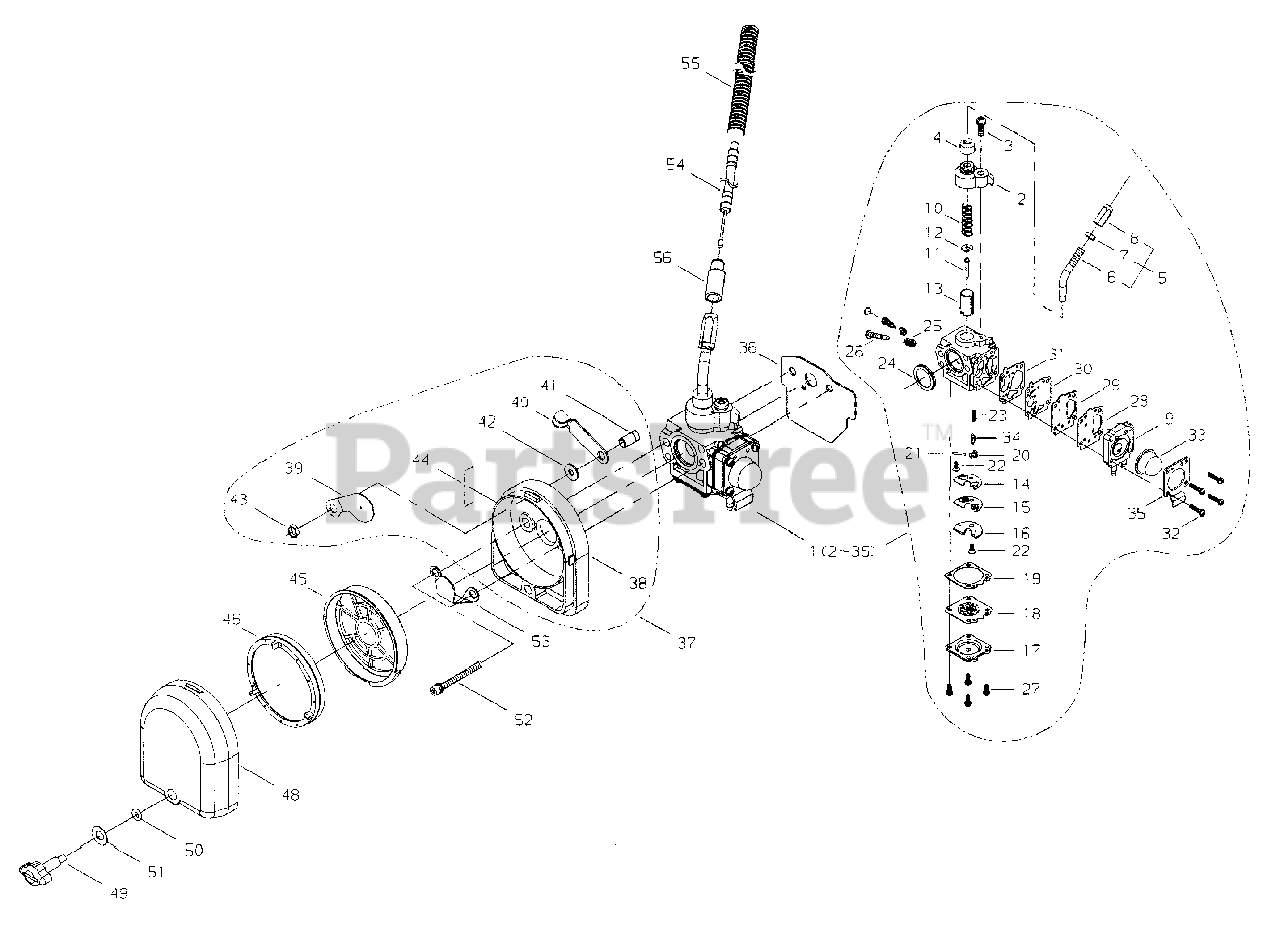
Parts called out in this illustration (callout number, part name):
1	CARBURETOR
2	CAP, CARBURETOR
3	SCREW M5×15
4	CAP, DUST
6	ADJUSTER ASSY, CABLE
7	NUT, LOCK
8	ADJUSTER, CABLE
9	COVER ASSY, PUMP
10	SPRING, THROTTLE
11	NEEDLE, JET
12	WASHER, SPRING SUPPORT
13	VALVE, THROTTLE
14	GASKET
15	VALVE, CHECK
16	PLATE
17	COVER, DIAPHRAGM
18	DIAPHRAGM, METERING
19	GASKET, METERING DIAPHRAGM
20	LEVER, METERING
21	PIN, METERING LEVER
22	SCREW M3×8
23	SPRING
24	RING, PACKING
25	SPRING
26	SCREW, IDLE ADJUST
27	SCREW M3×8
28	GASKET, FUEL PUMP
29	PLATE, FUEL PUMP
30	DIAPHRAGM, FUEL PUMP
31	GASKET, FUEL PUMP
32	SCREW M3×14
33	BULB, PURGE
34	VALVE, INLET NEEDLE
35	COVER, PUMP
36	GASKET, CARBURETOR
37	CASE ASSY, AIR FILTER
38	CASE, AIR FILTER
39	PLATE, CHOKE
40	LEVER, CHOKE
41	SHAFT, CHOKE
42	WASHER, CONE M6
43	U-NUT M6
44	LABEL, CHOKE
45	SCREEN, REAR AIR FILTER
46	FILTER, HEAVY-DUTY AIR
48	COVER, AIR FILTER
49	THUMBSCREW
50	O-RING
51	WASHER, CONE M6
52	BOLT M5×50
53	PLATE
54	CABLE, THROTTLE
55	TUBE, PLASTIC PROTECTIVE
56	CAP, CARBURETOR
